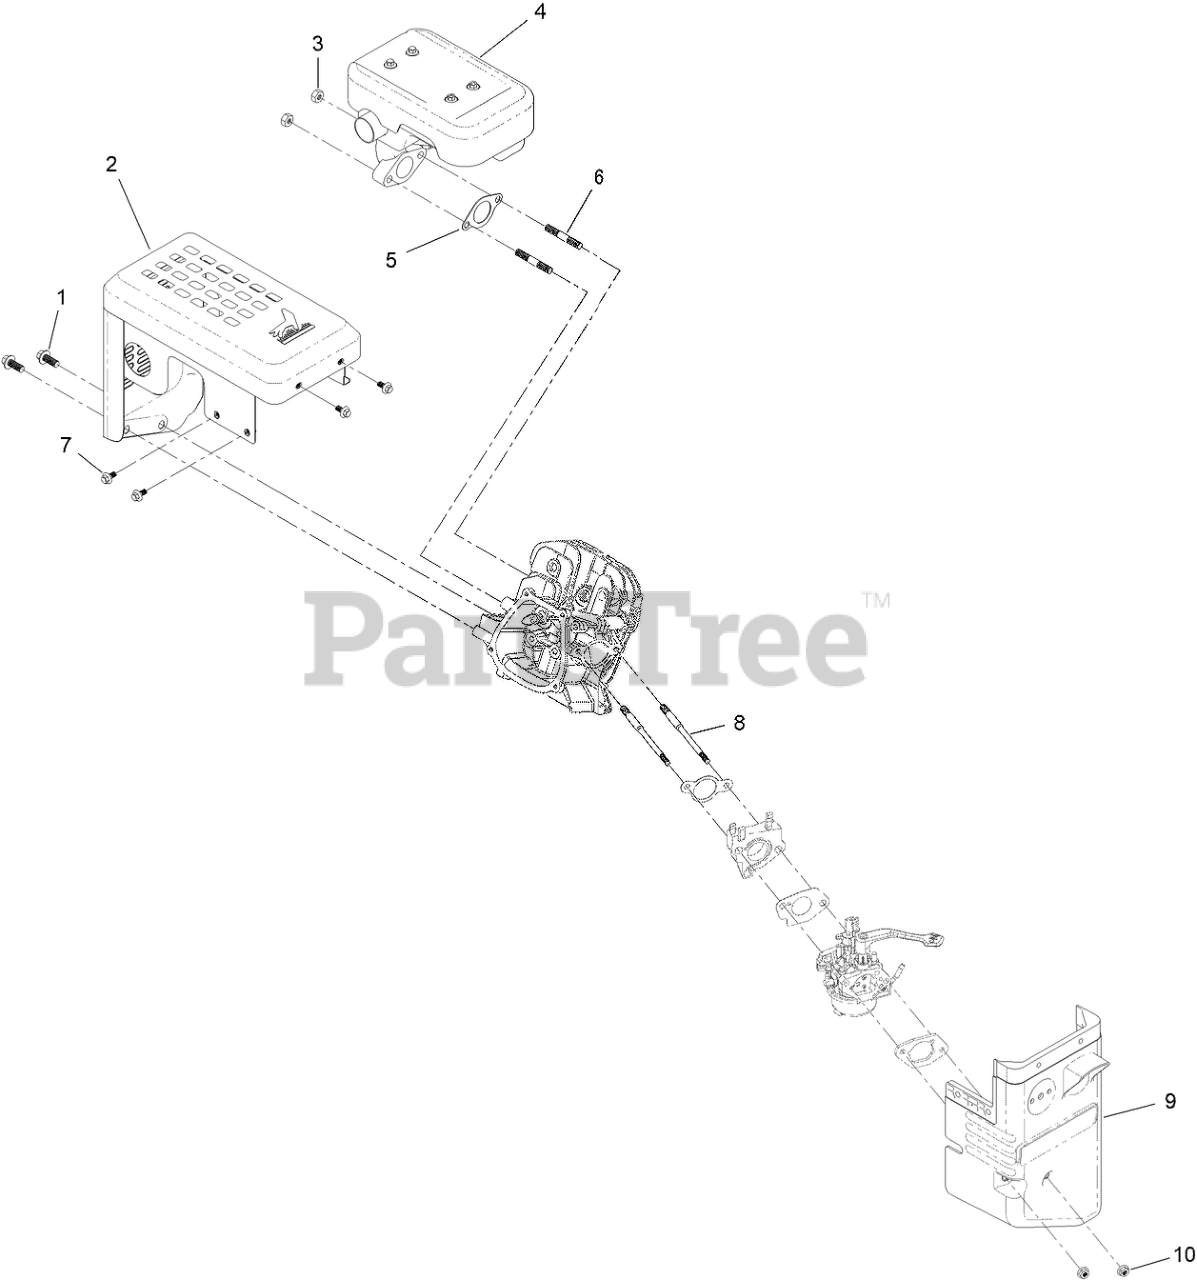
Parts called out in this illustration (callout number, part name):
1	SCREW-HHF
2	SHIELD-MUFFLER
3	NUT-HH
4	MUFFLER ASM
5	GASKET-EXHAUST
6	STUD-MOUNT, MUFFLER
7	SCREW-HHF
8	STUD-MOUNT, CARBURETOR
9	BOX-HEATER
10	NUT-FLANGE
